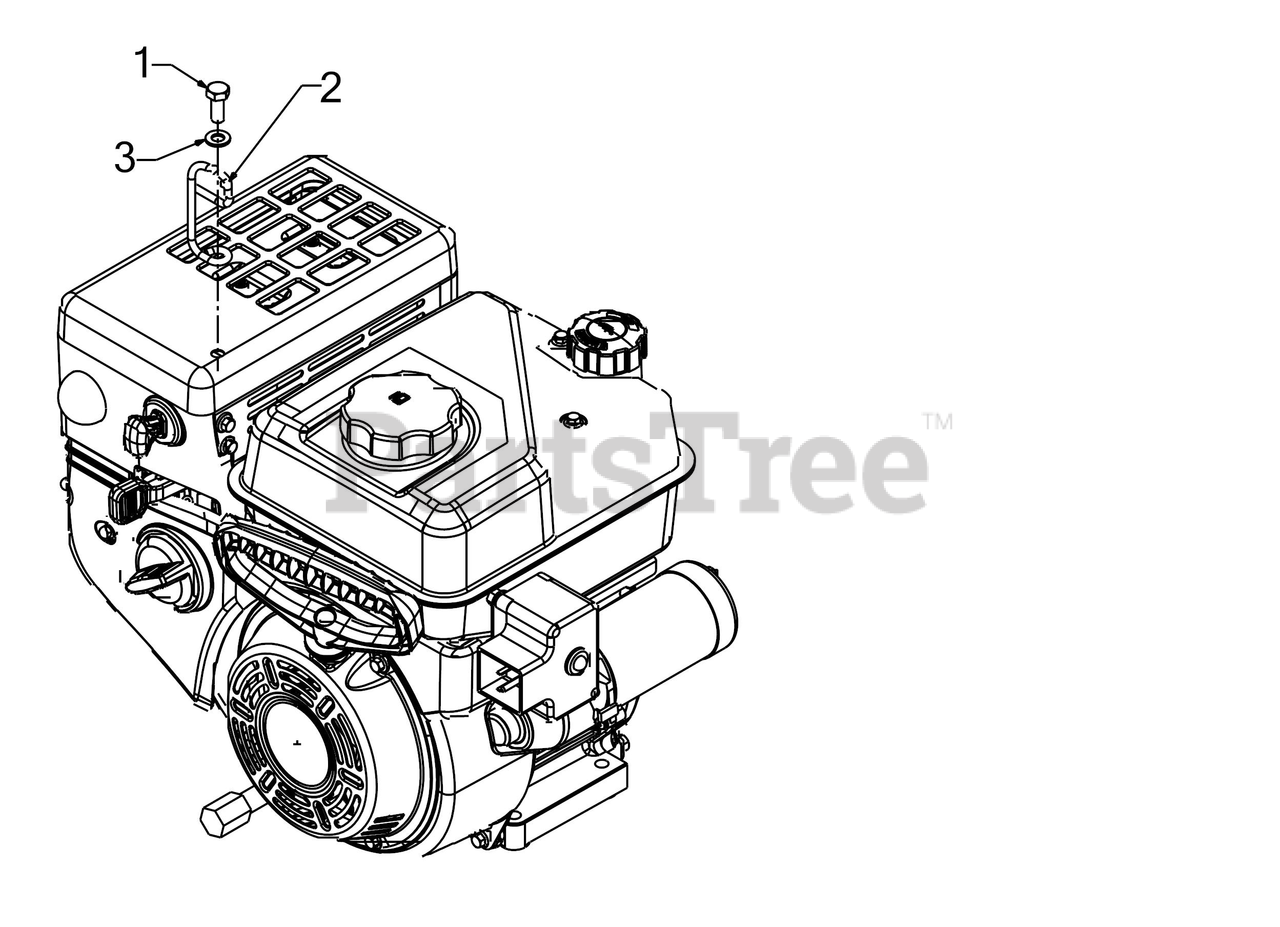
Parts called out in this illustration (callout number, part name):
1	HEX SCREW M8-1.25 x 20 GR8
2	CABLE CONTROL WIRE
3	FLAT WASHER
